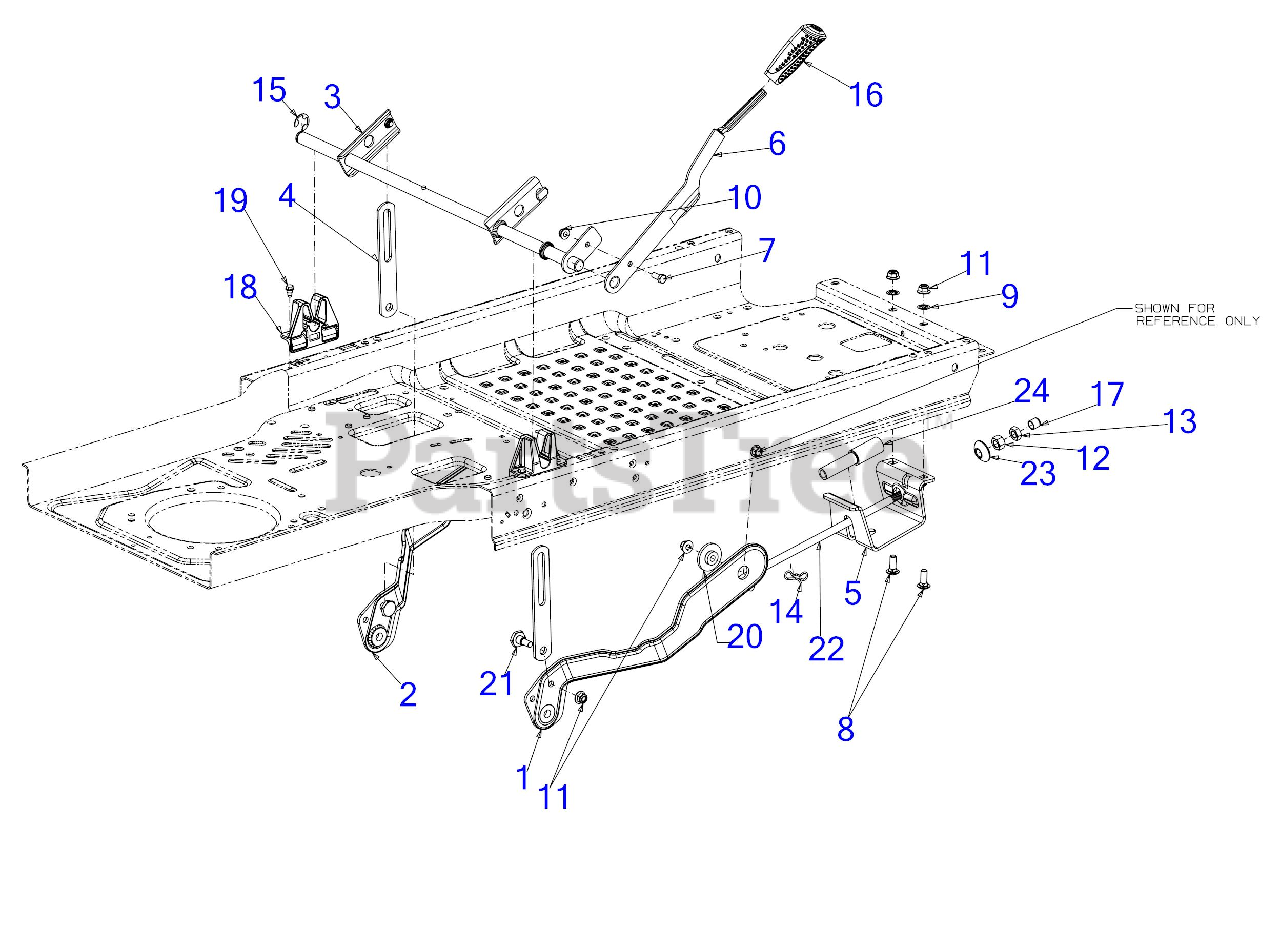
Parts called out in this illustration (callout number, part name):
1	DECK LIFT PLATE ASSEMBLY
2	DECK LIFT PLATE ASSEMBLY
3	DECK LIFT SHAFT ASSEMBLY
5	ROD SUPPORT BRACKET
6	DECK LIFT HANDLE
7	SCREW 5/16-18 x .75 GR5
8	CARRIAGE BOLT 3/8-16 x 1.00 GR5
10	FLANGE LOCK NUT 5/16-18
12	HEX NUT NYLOK 1/2-13
13	HEX NUT
14	BOW TIE COTTER PIN
15	E-RING
17	LIFT ROD END CAP
18	DECK LIFT BRACKET
19	SHOULDER SCREW 1/4-20X.50 19"PSH
20	SHOULDER SPACER -S
21	SHOULDER SCREW
22	FRONT LIFT DECK ROD
23	LIFT PIVOT CUP
24	SLEEVE .55 ID x 4.50 LG
